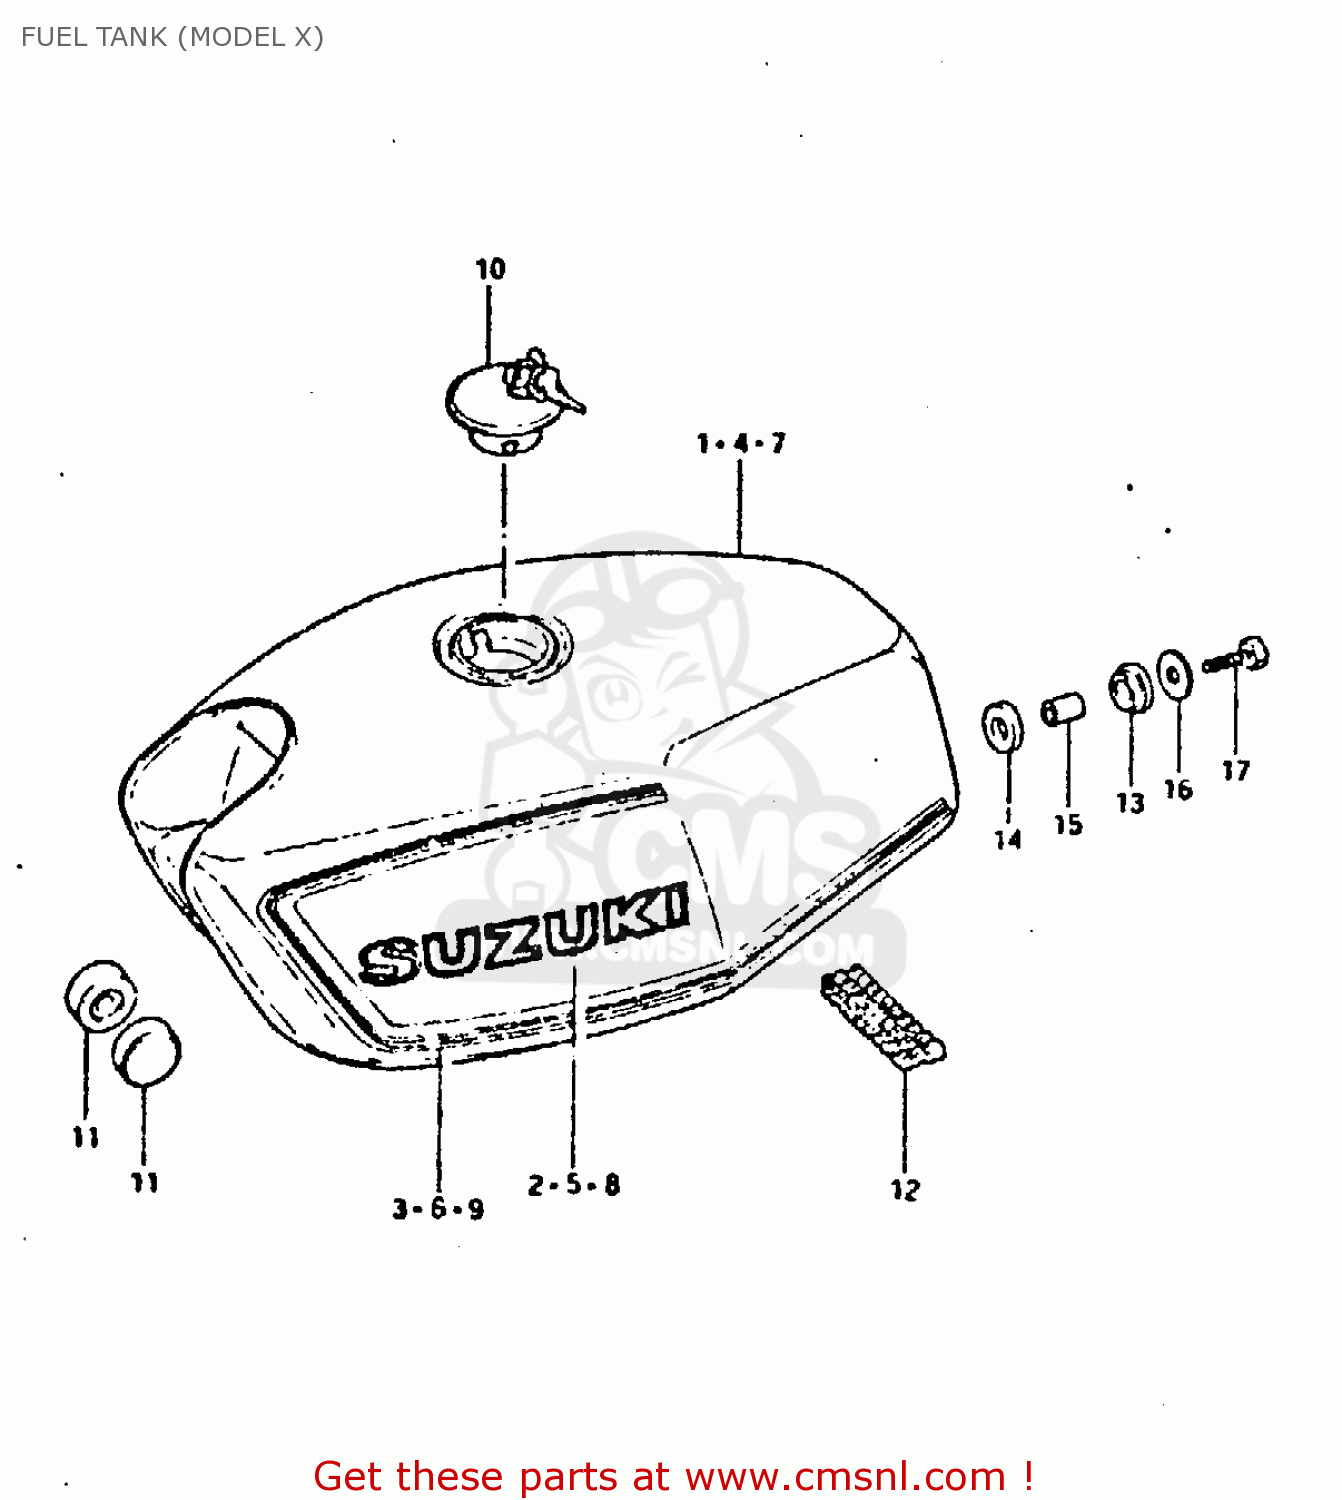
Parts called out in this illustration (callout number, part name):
1	TANK, FUEL (BLACK)
2	EMBLEM
3	TAPE SET
4	TANK, FUEL (RED)
5	EMBLEM
6	TAPE SET
7	TANK, FUEL (BLUE)
8	EMBLEM
9	TAPE SET
10	CAP SET,FUEL TANK
11	CUSHION
12	CUSHION
13	CUSHION
14	CUSHION
15	SPACER(8.5X12X19)
16	WASHER (8.5X29X1.6)
17	BOLT (8X30)
